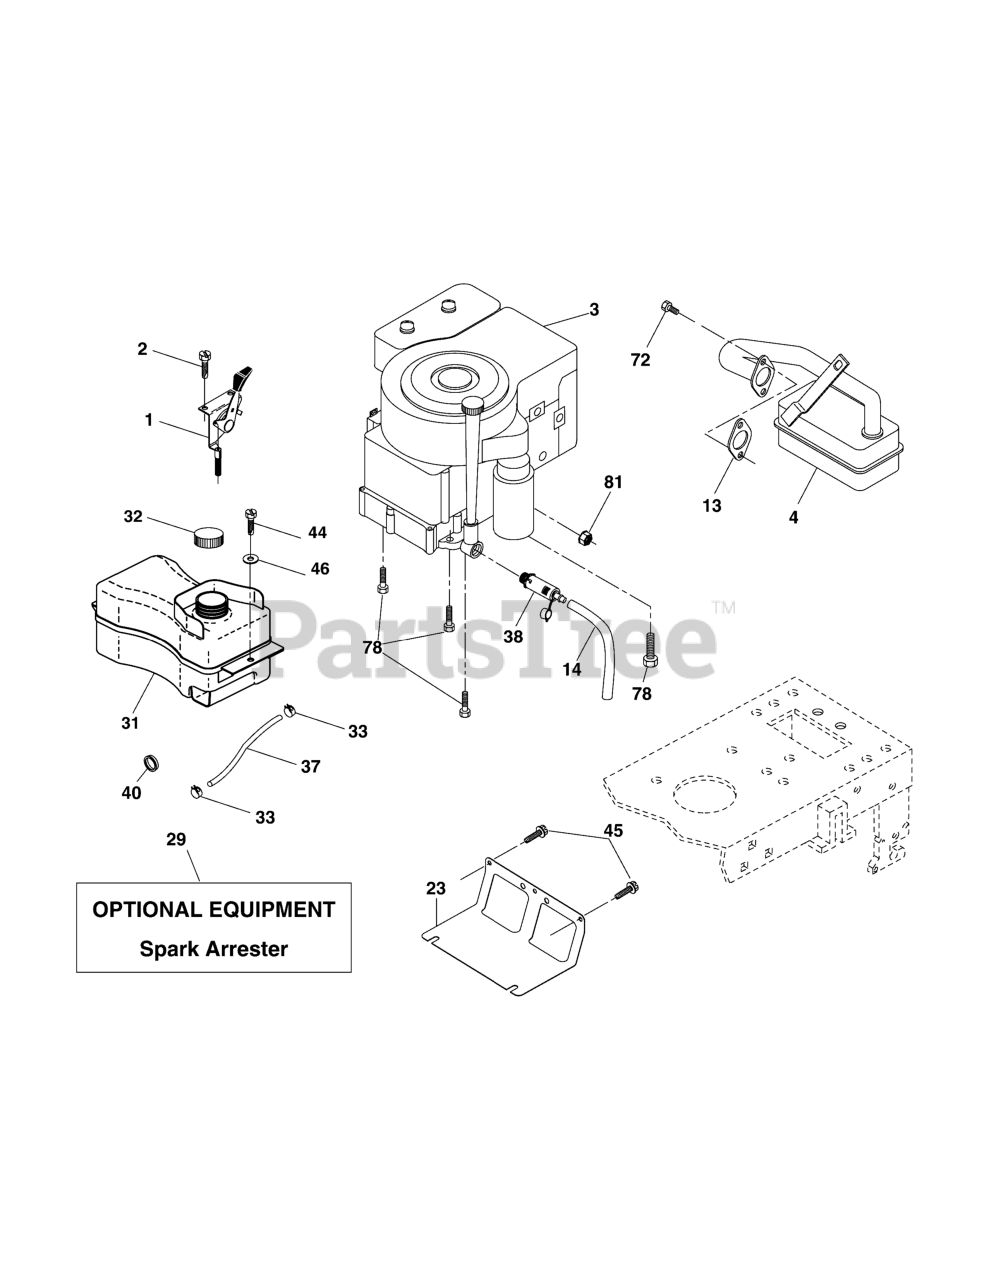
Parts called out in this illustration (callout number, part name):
1	** Control Th/ch Paddle
2	Screw Hex Thd Cut 1/4-20 x 1/2
3	Engine, B&S
4	Muffler Exhaust B&S
13	Gasket Eng 1 313 Id Tin Plated
14	Tube Drain Oil Easy
23	Shield BRN/DBR Guard
29	Kit Spark Arrestor (Flat Scrn)
31	Tank Fuel Front
32	Cap Fuel
33	Clamp Hose
37	Line Fuel 20"
38	Valve Drain Oil
40	Bushing Snap Nyl Blk Fuel Line
44	Screw Thdrol 1/4-20 x 3/4
45	Screw Hex Wsh Thdrol 3/8-16
46	Washer 9/32 x 7/8 x 16 Ga.
72	Screw Socket Head 5/16-18 x 3/4
78	Screw 3/8-16 x 1-1/4
81	Nut Keps Hex 1/4-20 unc
